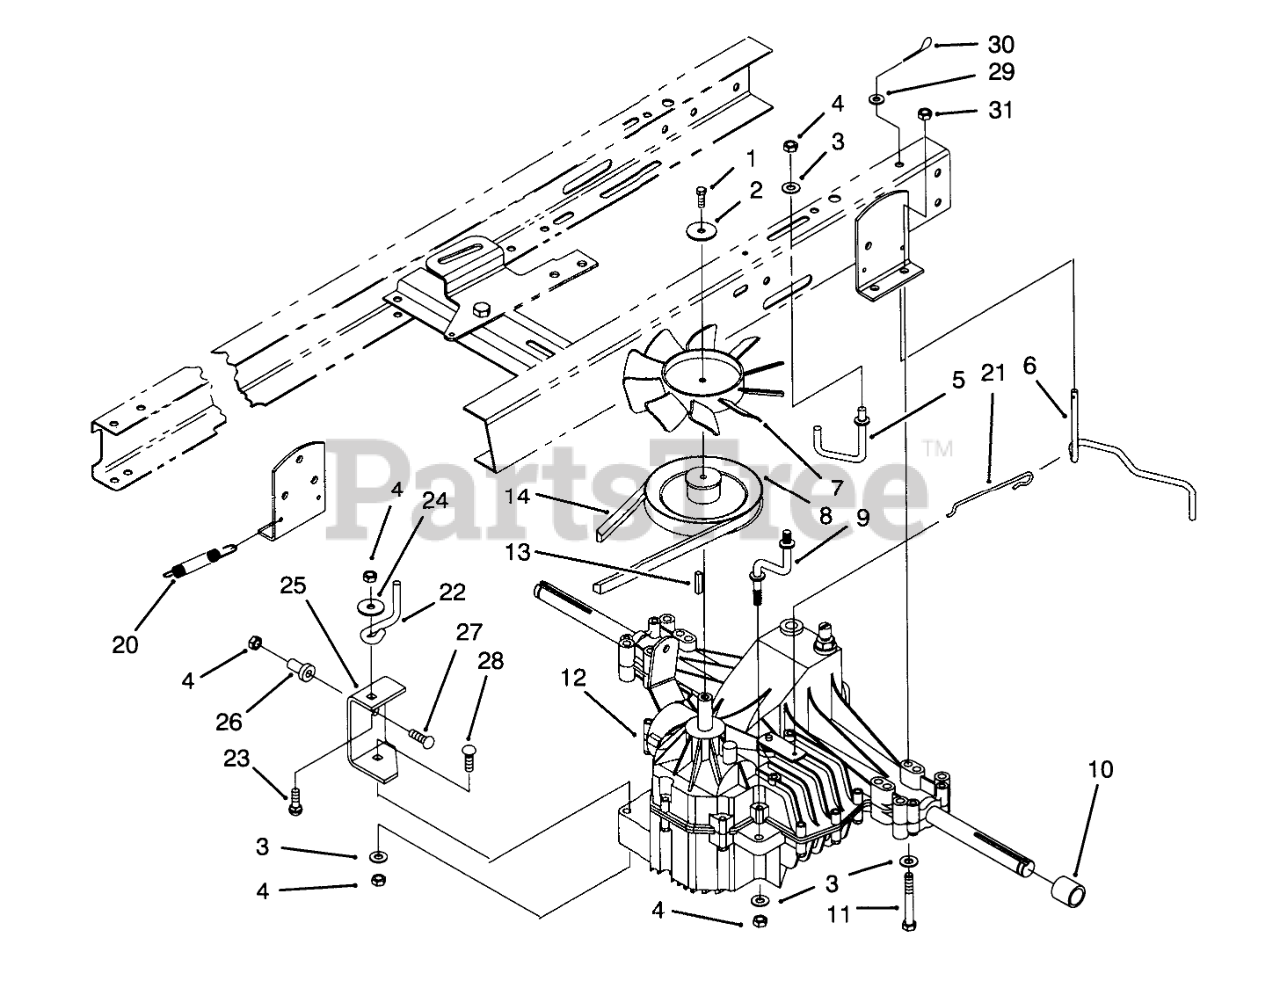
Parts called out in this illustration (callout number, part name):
1	SCREW-HH
2	WASHER-FLAT
3	WASHER-PLAIN
4	NUT-LOCK, NI
5	GUIDE-TRANS BELT, LH
6	LEVER - BYPASS
7	FAN-7"
8	HYDRO TRANS PULLEY
9	TORQUE STRAP
10	SPACER
11	SCREW-HH
12	Transaxle
13	KEY-PUMP
14	V-BELT
20	SPRING-RETURN, BRAKE
21	WIRE - BYPASS
22	TRANS BELT GUIDE
23	BOLT-CARR
24	WASHER-PIVOT
25	Bracket-Speed Control
26	BUSHING-FLANGE
27	SCREW-CARR
28	BOLT-CARR
29	WASHER-FLAT
30	PIN-COTTER
31	NUT-KEPS
